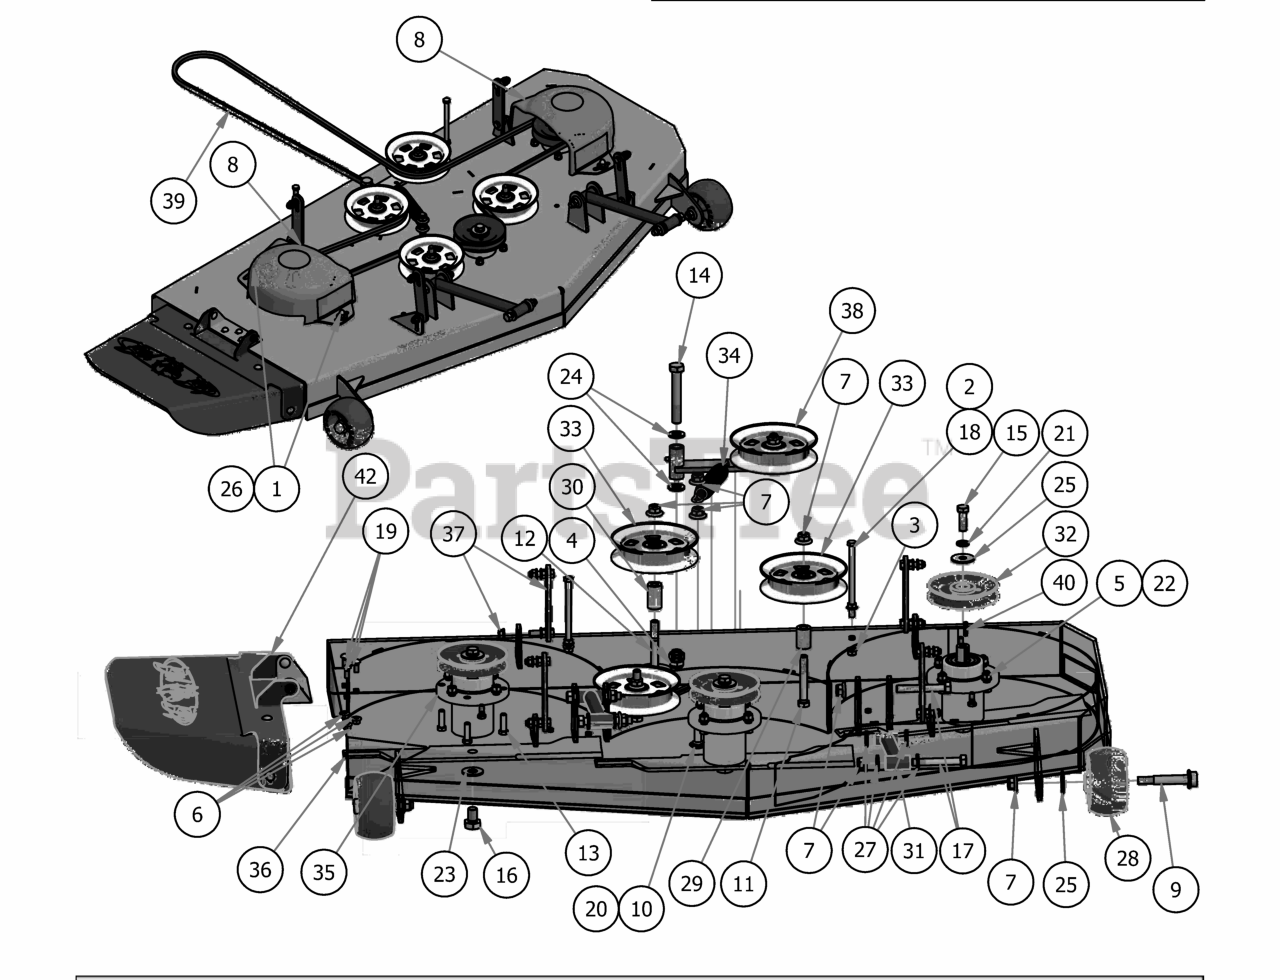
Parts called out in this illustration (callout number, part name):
1	Acorn nut-pulley Cover
2	3/8" Flange Nut
3	3/8" Nylock Flange Nut
4	5/8" Nylock (1/2 Jam)
5	3/8" Hex Nut
6	5/16" Nylon Flange Nut
7	1/2-13 Nylon Flange Nut
8	Pulley Cover
9	Deck Wheel Bolt
10	1/2 x 2" Carriage Bolt
11	1/2 x 3 1/2 Flange Bolt Grade 8
12	1/2" x 4" Bolt (Grade 8)
13	3/8" x 1 1/4" Hex Bolt
14	5/8" x 4" Hex Bolt
15	1/2"-20 x 1 1/2 - Grade 5 Fine Thread Bolt
16	5/8" x 1 1/2" Grade 8 Hex Bolt (Fine)
17	1/2-13 x 3 1/2 GR 5 Hex Bolt
18	3/8-16 x 5 1/2 Hex Bolt
19	5/16-18x3/4 carriage bolt
20	.517 Square Hole Round Washer
21	1/2" Lock Washer
22	3/8" Lock Washer
23	5/8'' Flat Washer
24	.630 ID Plastic Washer
25	1/2" Belleville Washer
26	.360 ID Plastic Washer-Black
27	.505 Nylon Spacer
28	Deck Wheel
29	.502 ID X .750 OD X 1.500 Long Spacer
30	1 3/4" Pulley Spacer
31	MZ/ZT Deck Locator
32	54 MZ Spindle Pulley
33	5-3/4 Idler Pulley
34	Deck Idler Spring
35	Spindle Assembly-MZ
36	54" MZ Fusion Blade
37	Deck Hanger Assembly
38	2017 54"/48" Deck Idler Assembly
39	B155.75 Deck Belt
40	3/16 x 1 Square Key
41	2017 54" MZ Magnum Deck
42	MZ Discharge Chute Assembly
